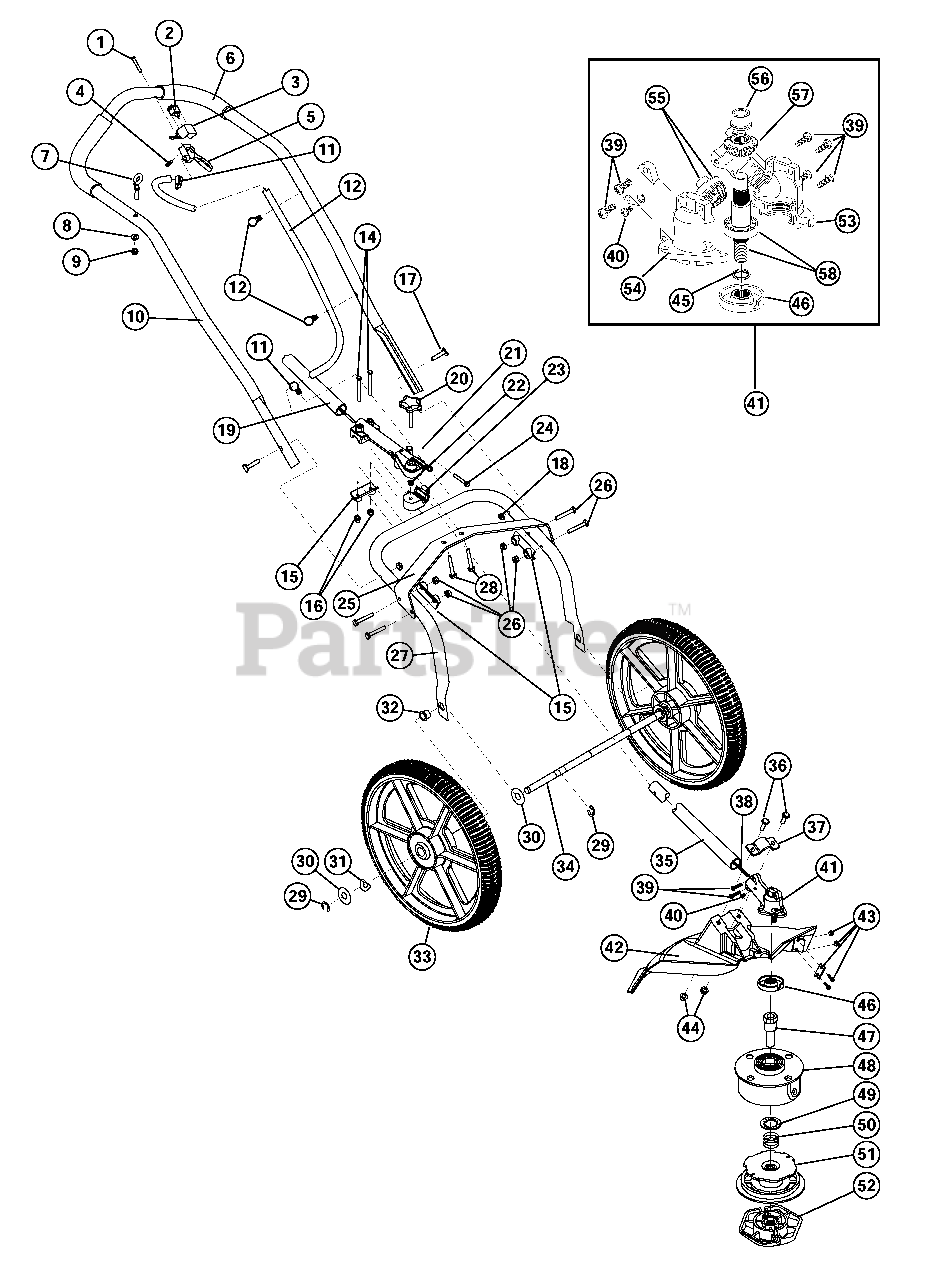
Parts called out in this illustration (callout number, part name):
1	Trigger Mount Screw
2	On/Off Switch 19
3	Switch Bracket
4	Weldnut
5	Throttle Trigger Assembly
6	Handlebar Grip
7	Rope Guide
8	Washer
9	Nut
10	Handlebar
11	Cable Tie
12	Wire Retaining Clip
13	Throttle Cable Cover
14	Hex Head Cap Screw
15	Retaining Clamp
16	Nut
17	Carriage Bolt
19	Upper Drive Shaft
20	Star Knob
21	Upper Clamp
22	Locknut
23	Clamp Grip
24	Bolt
25	Support Bracket
26	Hex Head Cap Screw
27	Lower Handlebar
29	E Ring
30	Washer
31	Spring Washer
32	Bushing
33	Wheel
35	Lower Drive Shaft Assembly
36	Bolt
37	Boom Mount Bracket
38	Drive Shaft
40	Anti-Rotation Screw
41	2 Piece Gearbox Assembly
43	Cutoff Blade Assembly
44	Locknut
45	O-Ring
47	Spool Shaft
48	Outer Spool & Eyelet Assembly
49	Retainer
51	Inner Reel
52	Bump Knob Assembly w/Bolt
53	Left Housing
54	Right Housing
55	Pinion Gear Assembly
56	Output Shaft Bushing
57	Output Shaft Gear
58	Output Shaft Assembly
